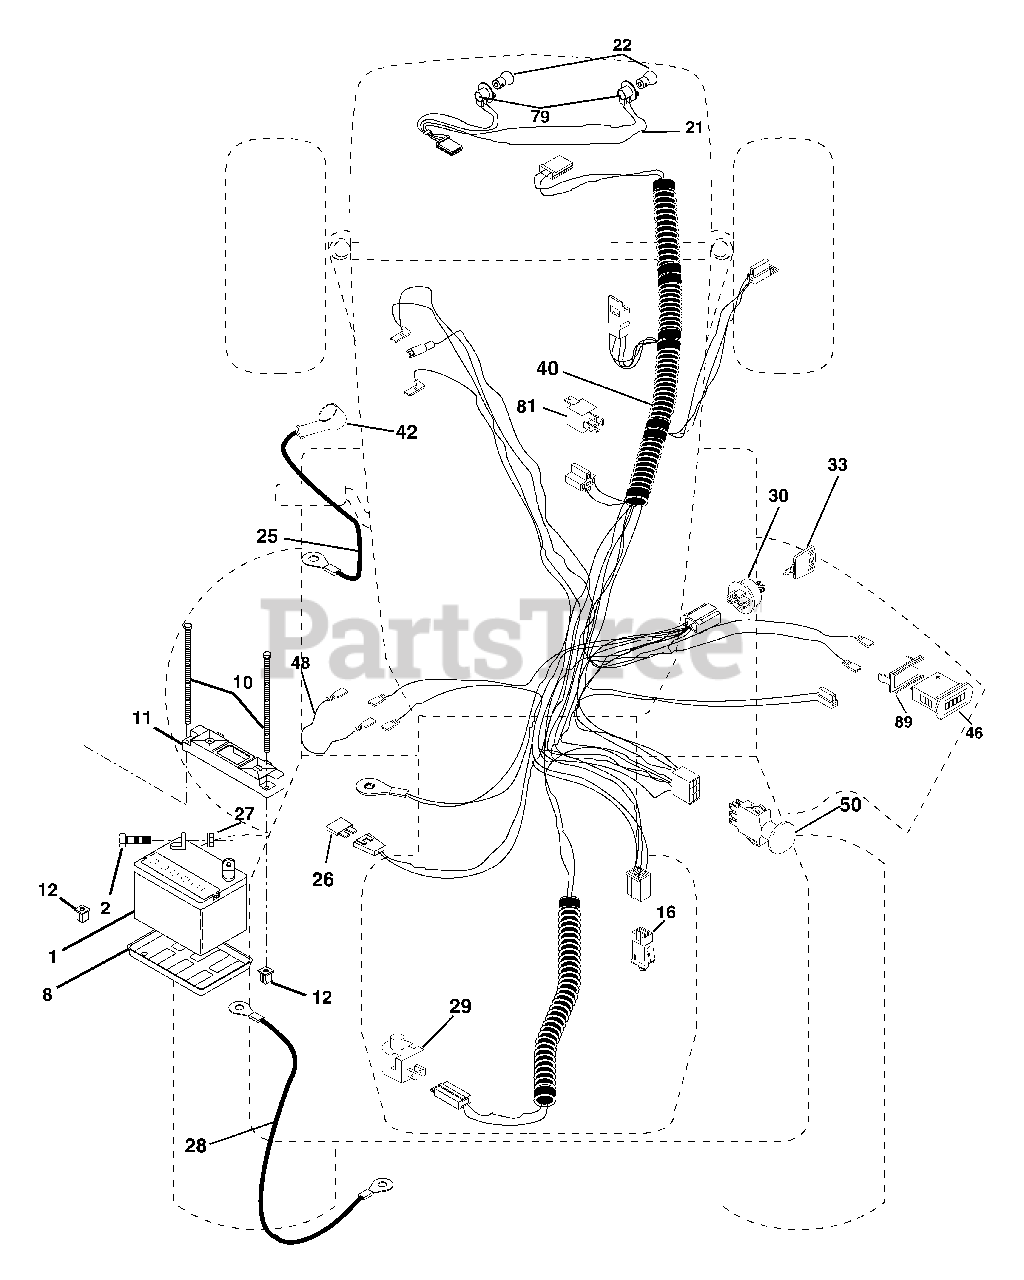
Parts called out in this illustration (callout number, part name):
1	Battery
2	Bolt Hex Head 1/4-20 x 3/4
8	Tray, Battery
10	Bolt, Battery Front 1/4-20 x 7.5 Zinc
11	Holddown Battery Front Mount
12	Nut, Push Nylon 1.4" Battery Front
16	Switch Interlock
21	Harness Socket Light w/4152J
22	Bulb Light
25	Cable, Battery
27	Nut Keps Hex 1/4-20
28	Cable, Ground
29	Switch, Plunger Normal Op Olive
30	Switch, Ign
40	Harness Ign.
42	Cover, Terminal Red
46	Hourmeter Snap-In
48	Adapter Ammeter
50	Switch, PTO
79	Bulbholder Asm
81	Relay Asm.
89	Bracket Snap-In Hourmeter
